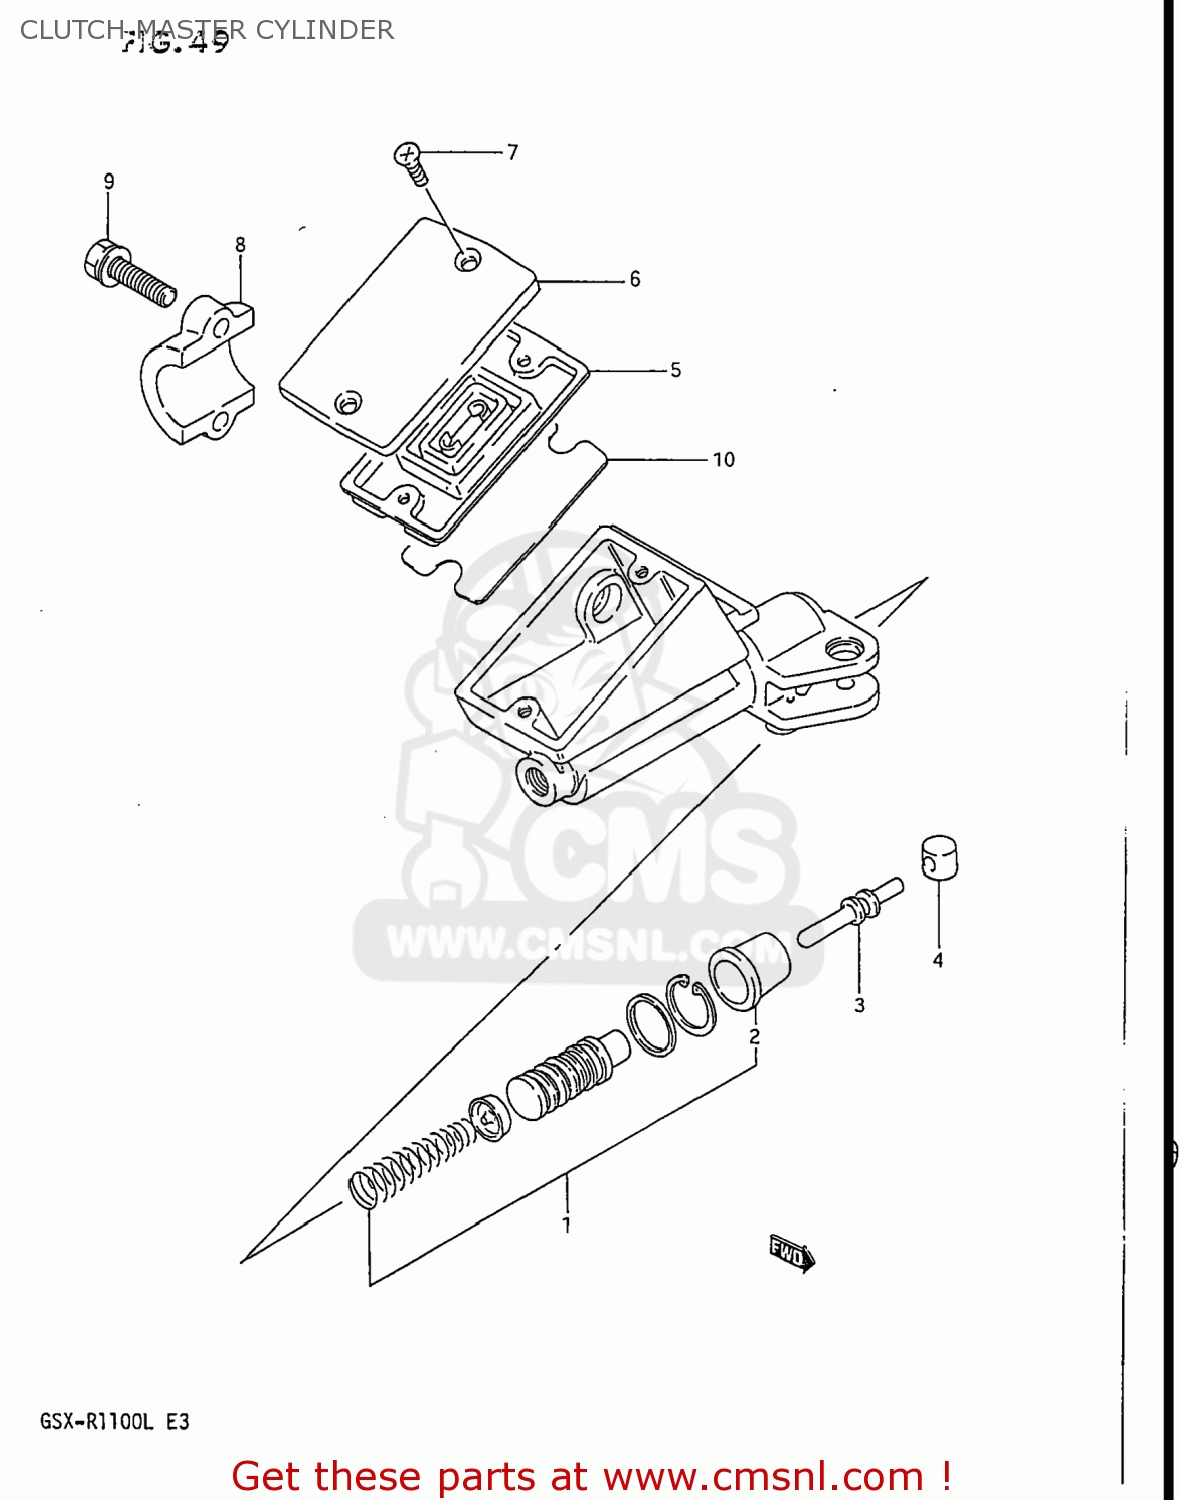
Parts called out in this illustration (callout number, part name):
1	PISTON & CUP SET
2	BOOT
3	ROD,PUSH
4	BUSH
5	6-1
6	CAP
7	SCREW
8	HOLDER
9	BOLT
10	FLOAT
